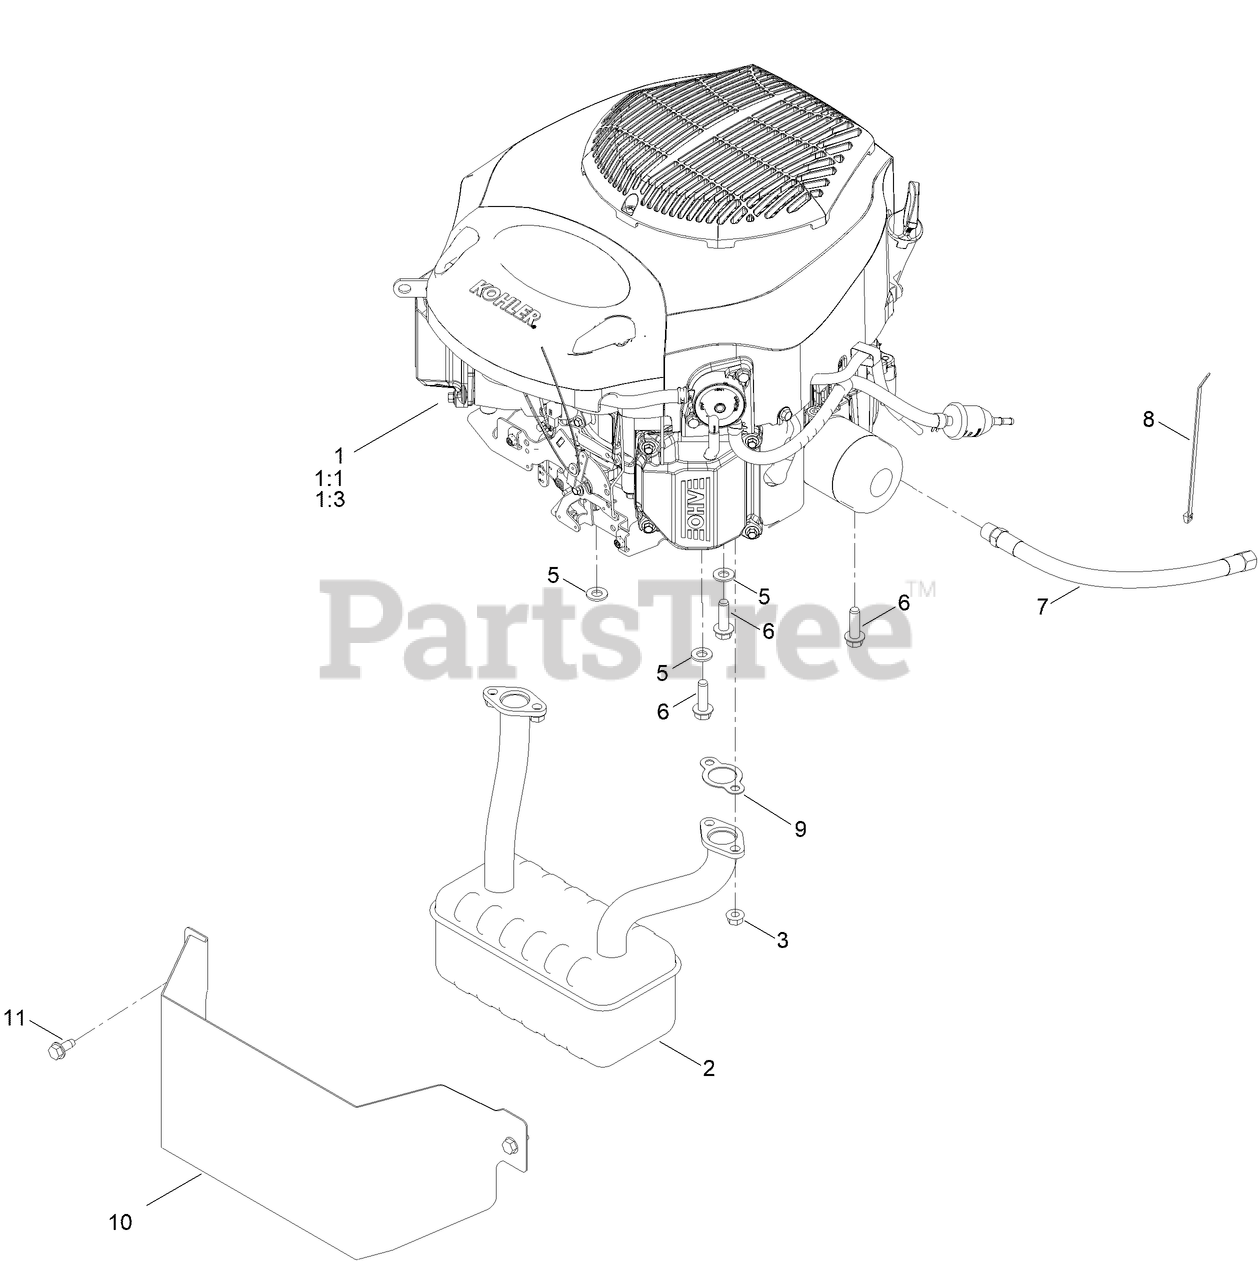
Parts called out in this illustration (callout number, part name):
2	MUFFLER
3	NUT-HF
5	WASHER-FLAT
6	SCREW-THD
7	HOSE-DRAIN, OIL
8	TIE-CABLE
9	GASKET-EXHAUST
10	HEAT SHIELD - MUFFLER
11	SCREW-HWHTF
